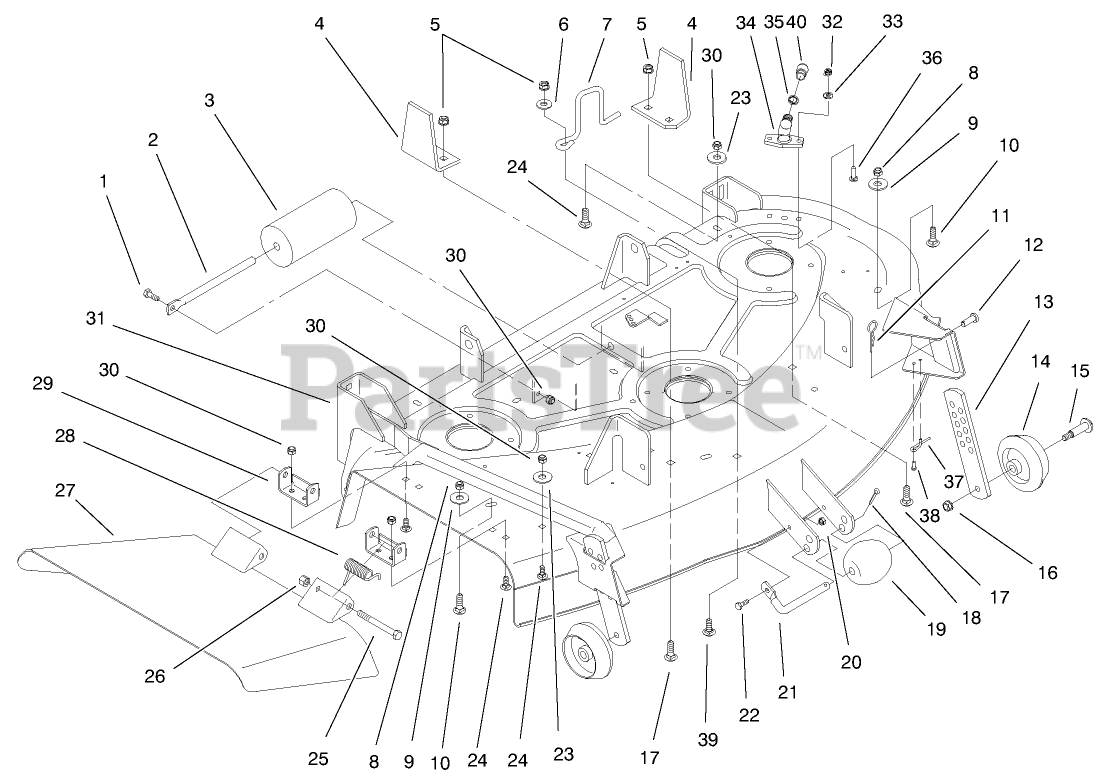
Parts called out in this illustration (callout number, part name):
1	SCREW-HH
2	ROD-ROLLER
3	ROLLER-DECK
5	NUT-LOCK, NI
6	WASHER
8	NUT-LOCK, NI
9	WASHER-FLAT
10	SCREW-CARR
11	PIN-HAIR
12	PIN-CLEVIS
13	PLATE-GAGE WHEEL
14	WHEEL-GAGE
15	SCREW-SHOULDER, HWH
17	BOLT-CARR
18	PIN-COTTER
19	ROLLER
20	NUT-LOCK, NI
21	SHAFT-ROLLER
22	SCREW-HH
23	WASHER-FLAT
24	SCREW-CARR
25	SCREW-HH
26	NUT-HEX
27	DEFLECTOR ASM
28	SPRING
29	BRACKET-PIVOT
30	NUT-LOCK, NI
31	Deck ASM w/Decals
32	NUT-LOCK, NI
33	WASHER-FLAT
35	O-RING
36	BOLT-CARR
37	SPRING-GAGE WHEEL
38	SCREW-HWHTF
39	SCREW-CARR
40	CONNECTOR-HOSE
